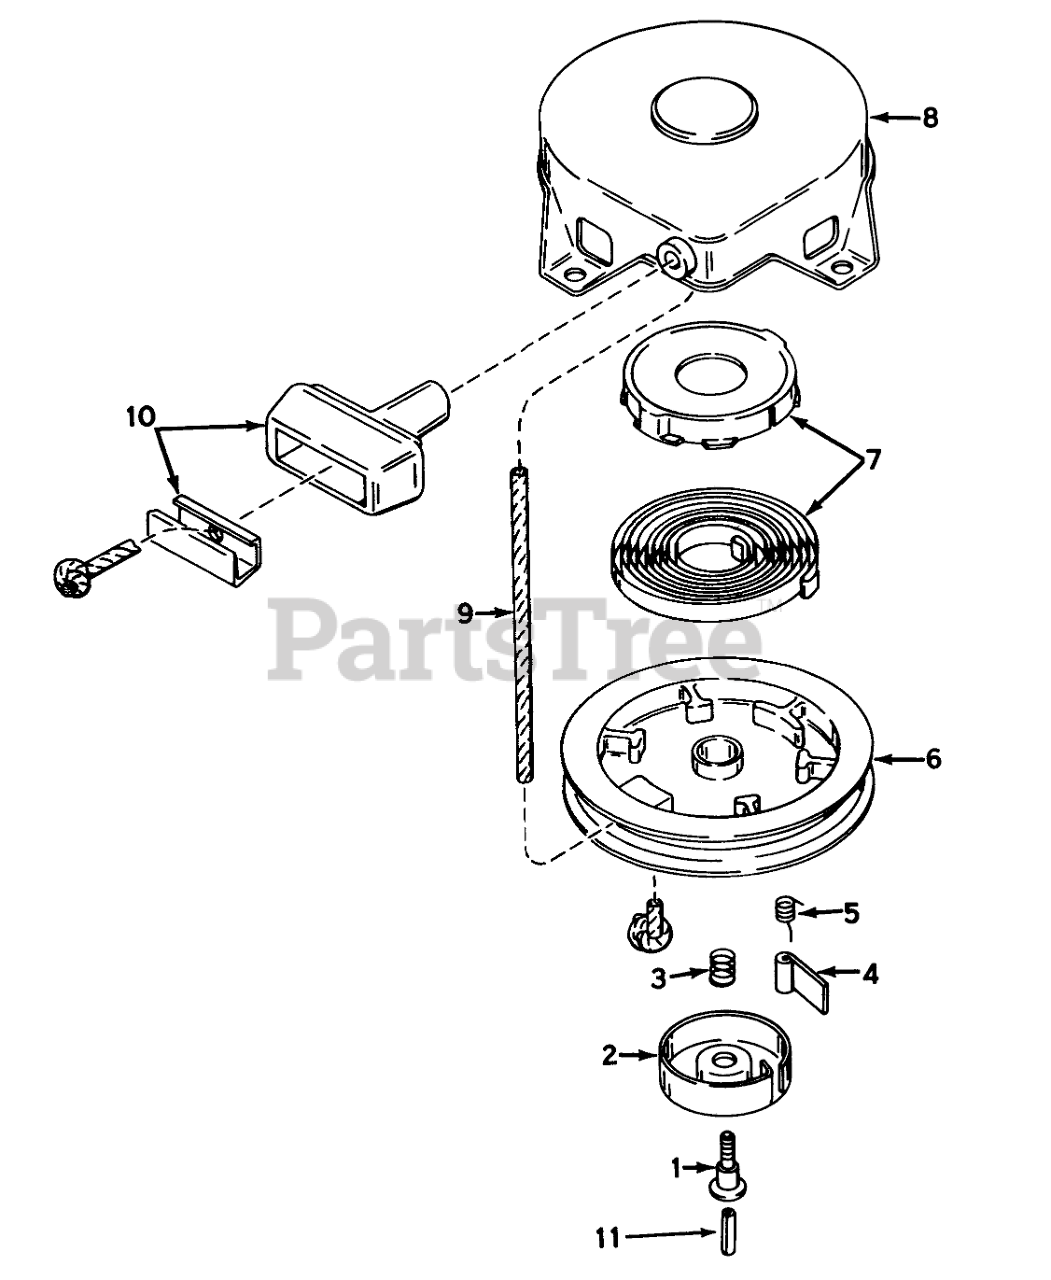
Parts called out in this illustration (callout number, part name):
1	Screw
2	Retainer
3	Spring-Brake
4	Dog-Starter
5	Spring-Dog
7	Spring & Keeper Assy
8	STARTER HOUSING ASSY
9	Rope Starter
10	Assy., Starter
11	Centering
